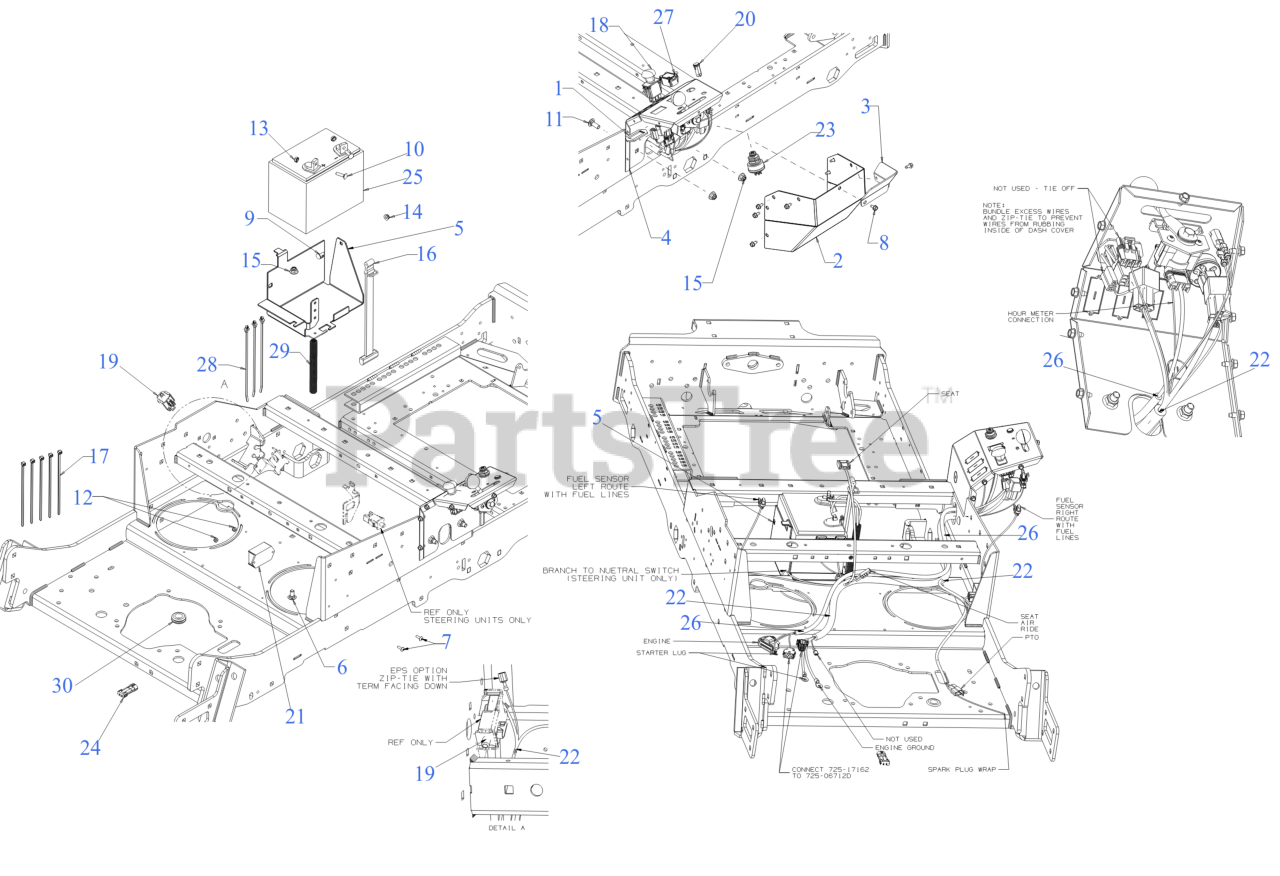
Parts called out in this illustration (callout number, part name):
1	BRACKET-PTO SWITCH
4	CONTROL POD (RH)
5	BATTERY MOUNTING BRACKET
5	BATTERY MOUNT BRACKET
6	CARRIAGE BOLT 3/8-16 x .750 GR5
7	SCREW #10-24 x .62
8	SCREW 1/4-20 X.500
9	SCREW 1/4-20 x .75 GR5
10	SCREW 1/4-20 x 1 GR5
11	CARRIAGE BOLT 3/8-16 x 1.00 GR5
13	SEMS NUT 1/4-20
14	FLANGE LOCK NUT
16	BATTERY RETAINER STRAP
17	7" CABLE TIE
18	PTO SWITCH (BLACK KNOB) TEXT SYM
19	3 POLE SWITCH ( NC-NO-NO)
20	INDICATOR LIGHT-RED
21	CONTROL PANEL (SOFT CLUTCH)
22	WIRE HARNESS ASSEMBLY (KOH/KAW EFI)
23	KEY SWITCH (3 POSITION)
23	PRO-Z KEY SET
24	SEALED CAP ASSEMBLY
25	BATTERY (230 CCA AGM U1-280)
26	HARNESS ADAPTER (KAW EFI)
27	HOUR METER
28	CABLE TIE
29	CONVOLUTED CONDUIT 1"
30	RUBBER GROMMET
